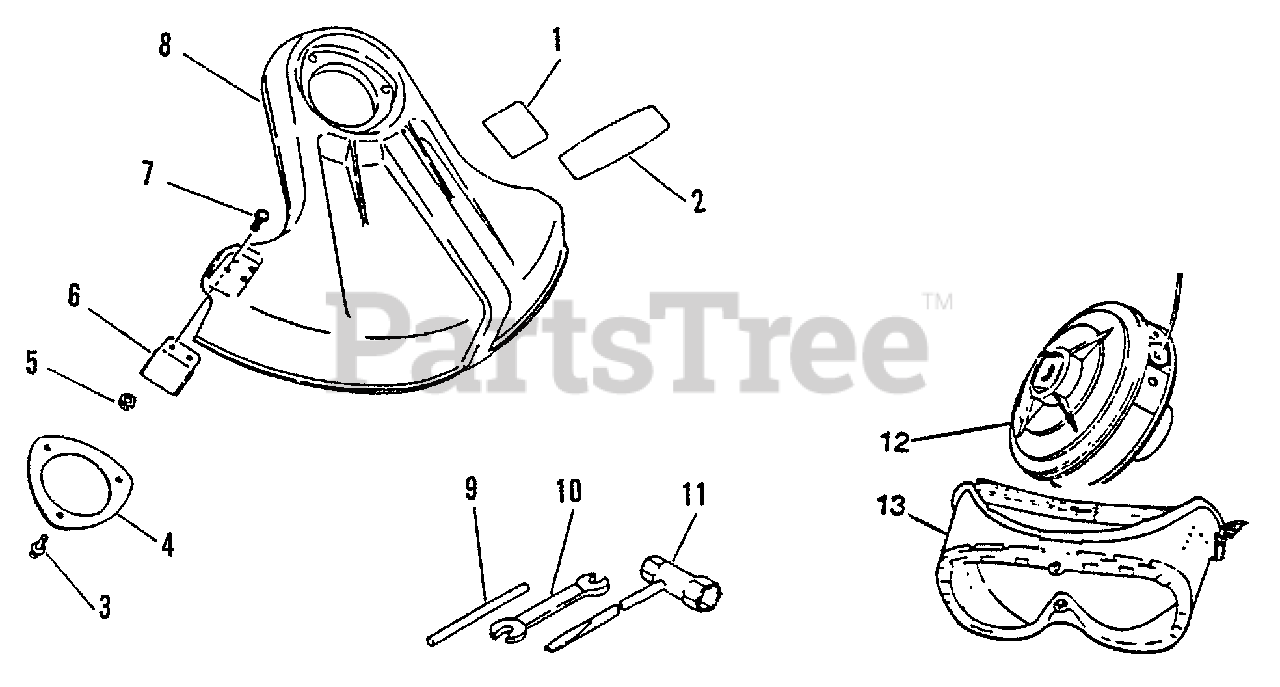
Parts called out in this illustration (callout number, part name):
1	Label, Caution
2	Label, Echo
3	Screw 5x16
4	Bracket, Shield
6	Knife, Cord
7	Screw 5x16
8	Shield
9	Locking Tool
10	Spanner 8x10
11	Wrench, W/Screw Driver
12	Cutter Asy, Line
